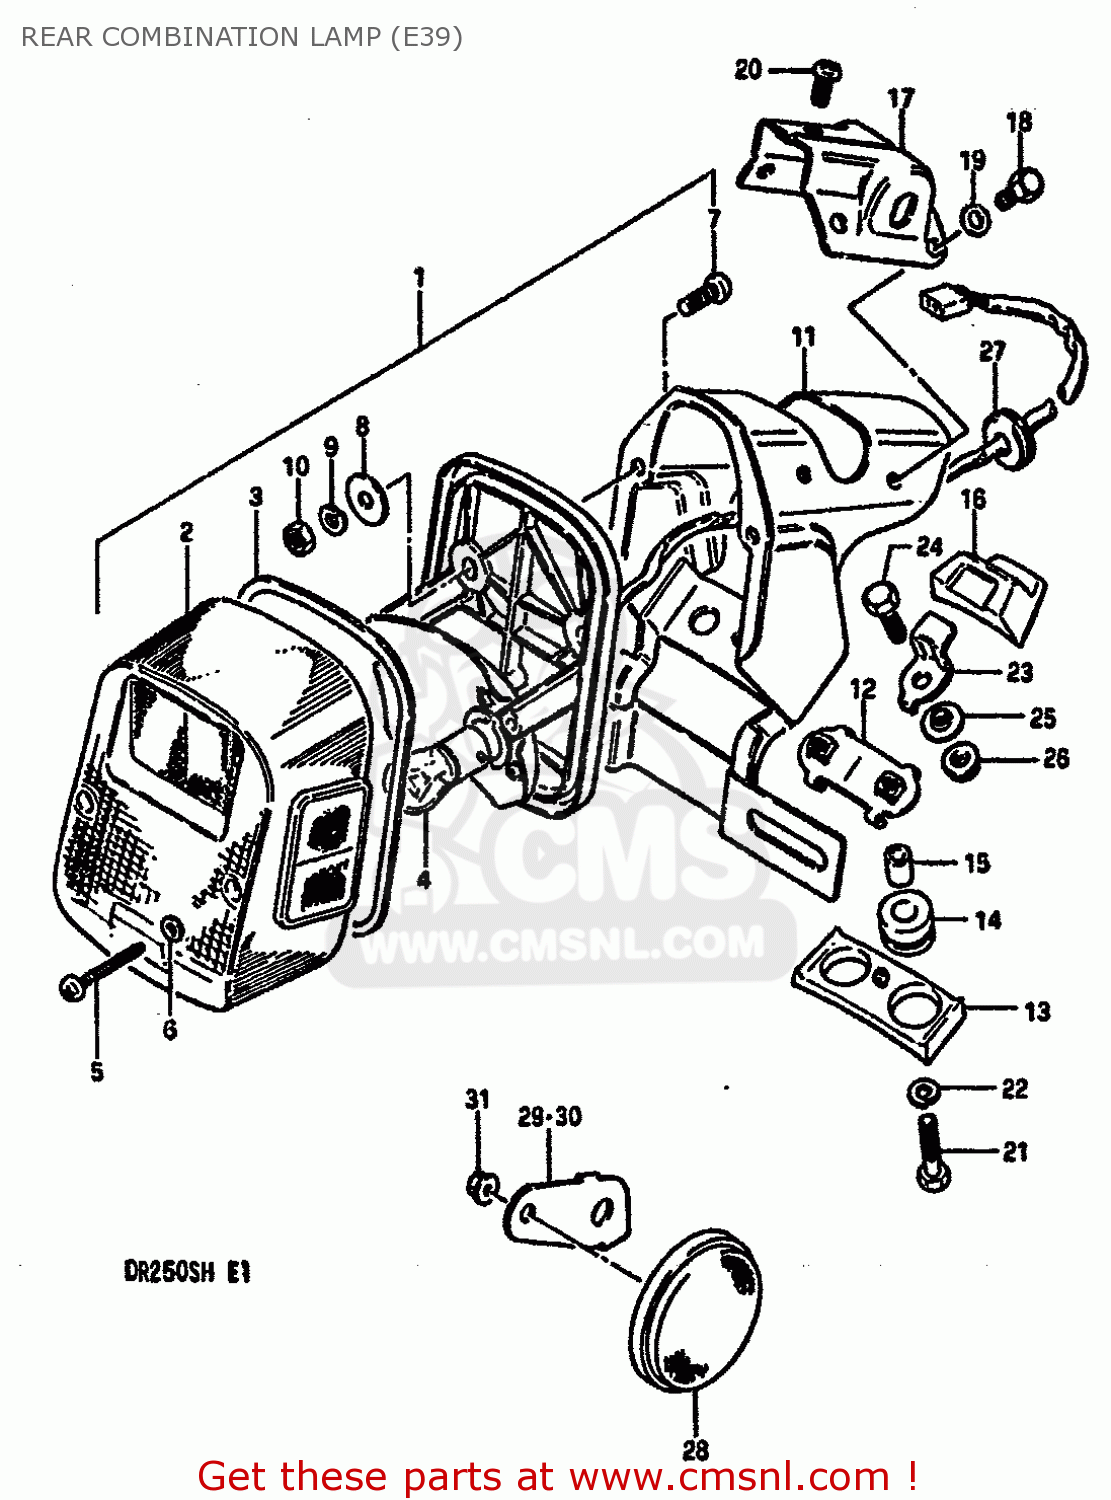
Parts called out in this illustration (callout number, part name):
1	LAMP UNIT,RR COMBNATION
2	LENS
3	GASKET (NAS)
4	BULB 12V21/5W
5	SCREW
6	GASKET (NAS)
7	SCREW
8	WASHER,REAR COMBINATION LAMP
9	LOCK WASHER
10	NUT
11	BRACKET UNIT
12	PLATE
13	CUSHION
14	CUSHION
15	SPACER
16	CUSHION,REAR COMBINATION LAMP
17	PLATE
18	BOLT
19	WASHER
20	SCREW 6X12
21	BOLT
22	WASHER,LOCK
23	PLATE,RR COMBINATION LAMP
24	BOLT
25	WASHER,LOCK
26	NUT
27	GROMMET
28	REFLECTOR,REFLEX FR
29	BRACKET,RH
30	BRACKET,LH
31	NUT ,5MM
